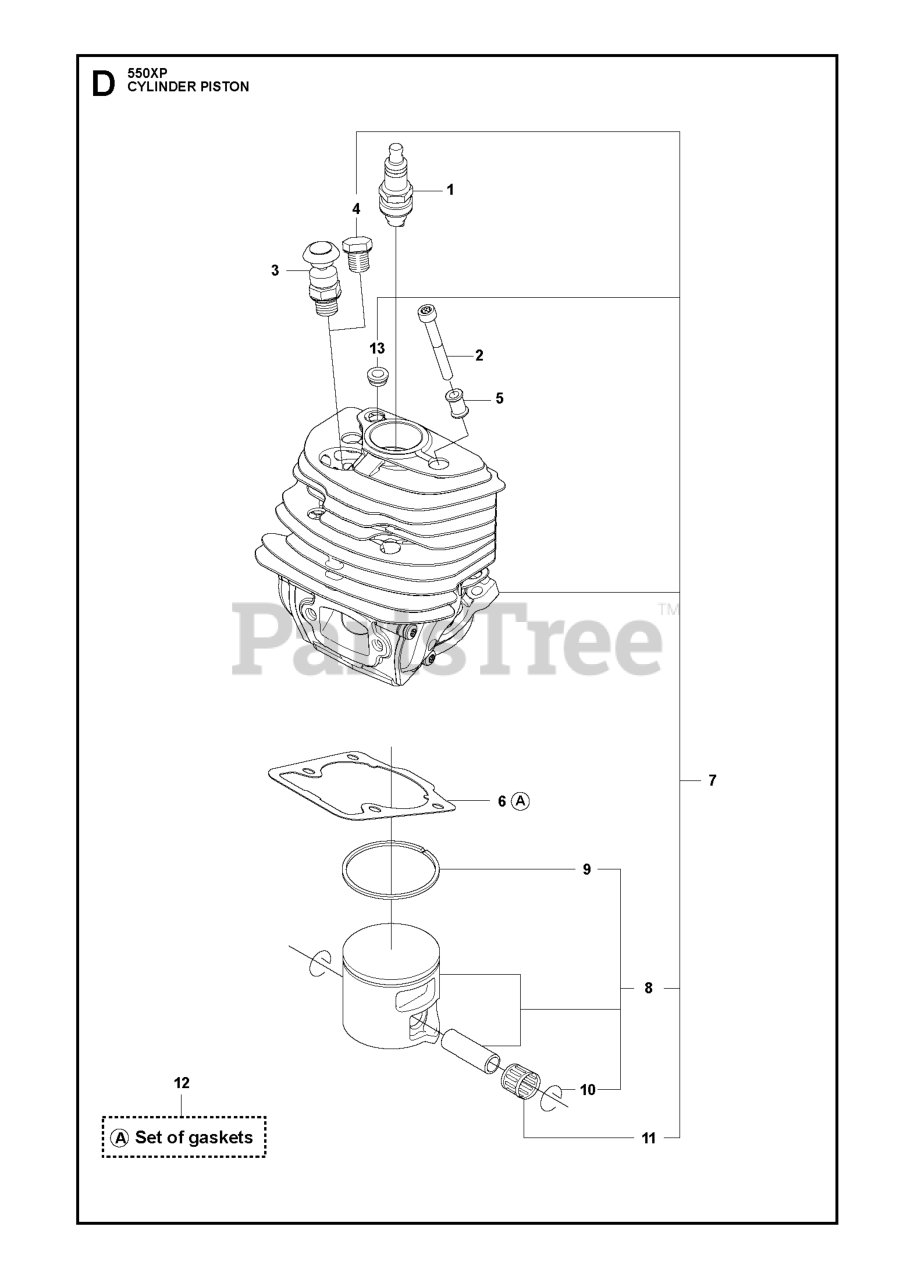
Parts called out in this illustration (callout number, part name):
1	CMR6H SPARK PLUG NGK
2	SCREW HEXABOULAR SOCKET HEAD C
3	DECOMPRESSION VALVE
4	CYLINDER PLUG
7	CYLINDER ASSY WITH PISTON H550
8	PISTON ASSY D43
9	PISTON RING
10	LOCKING RING
11	SUPPORT BUSHING
12	GASKET KIT 50CC
